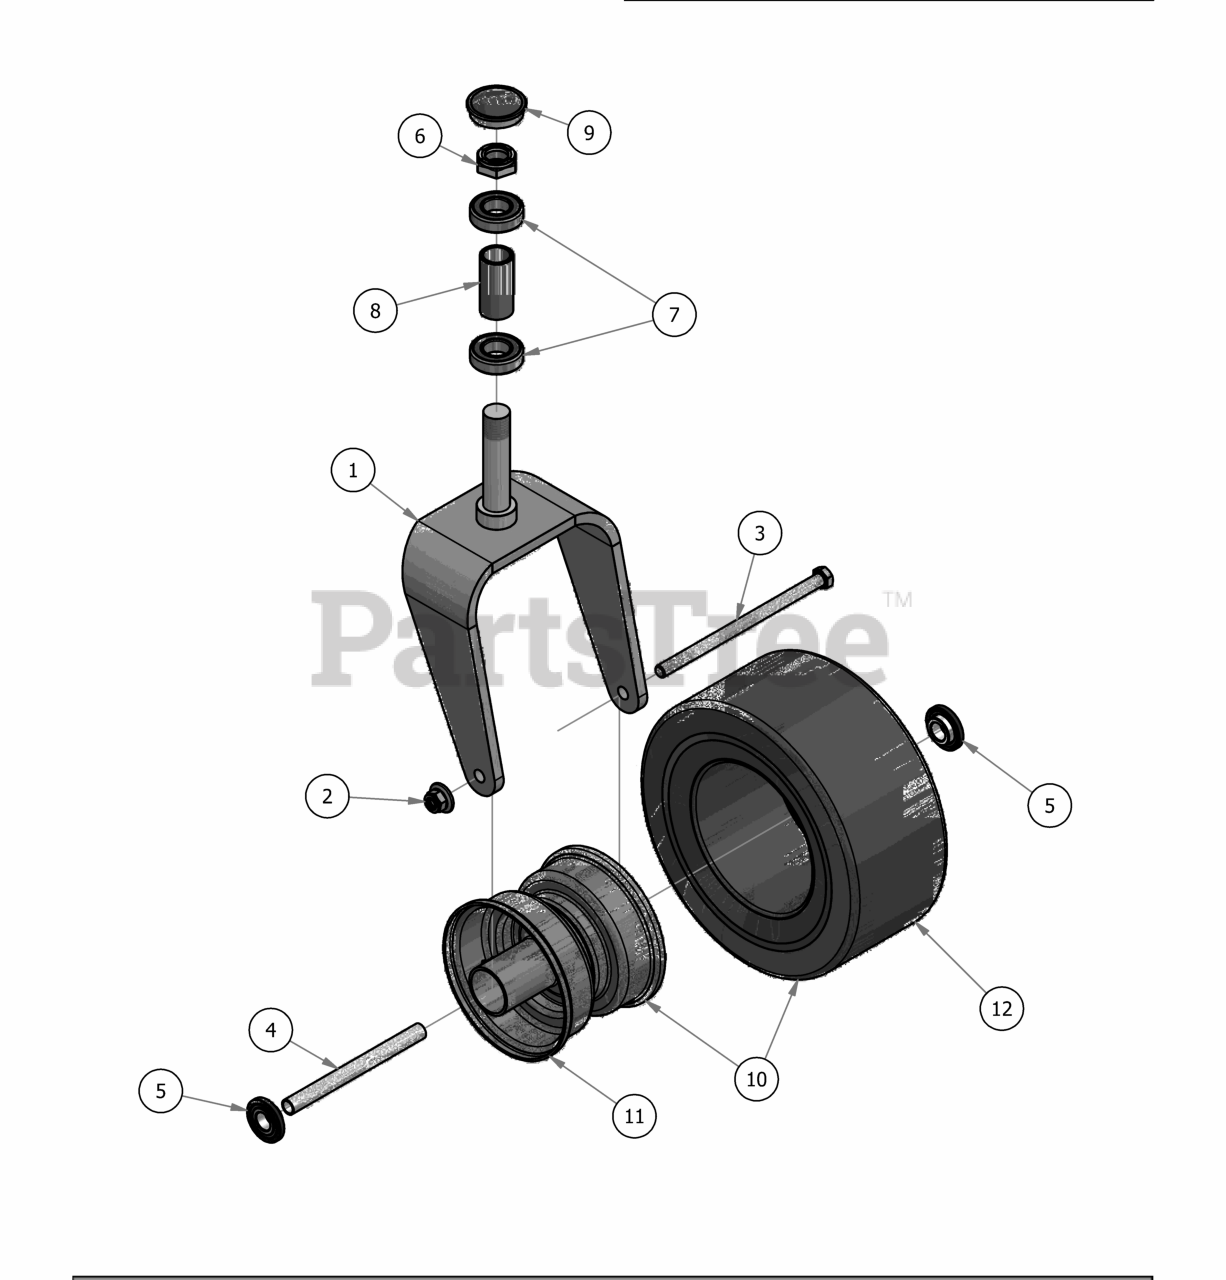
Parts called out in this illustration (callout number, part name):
1	Front Fork
2	1/2-13 Nylon Flange Nut
3	1/2" x 9" GR 5 Hex Bolt
4	Front Wheel Spanner
5	1-3/4" Bearing-Large Bore Front Rim
6	1" Fine Thread 1/2 Nylock Nut
7	Caster Bearing 2016 - 1641 Bearing
8	2016 Front Bearing Spacer
9	2017 Bearing Cover
10	Tire and black wheel assembly
11	6" Front Black Wheel
12	13 x 6.50 - Tire
